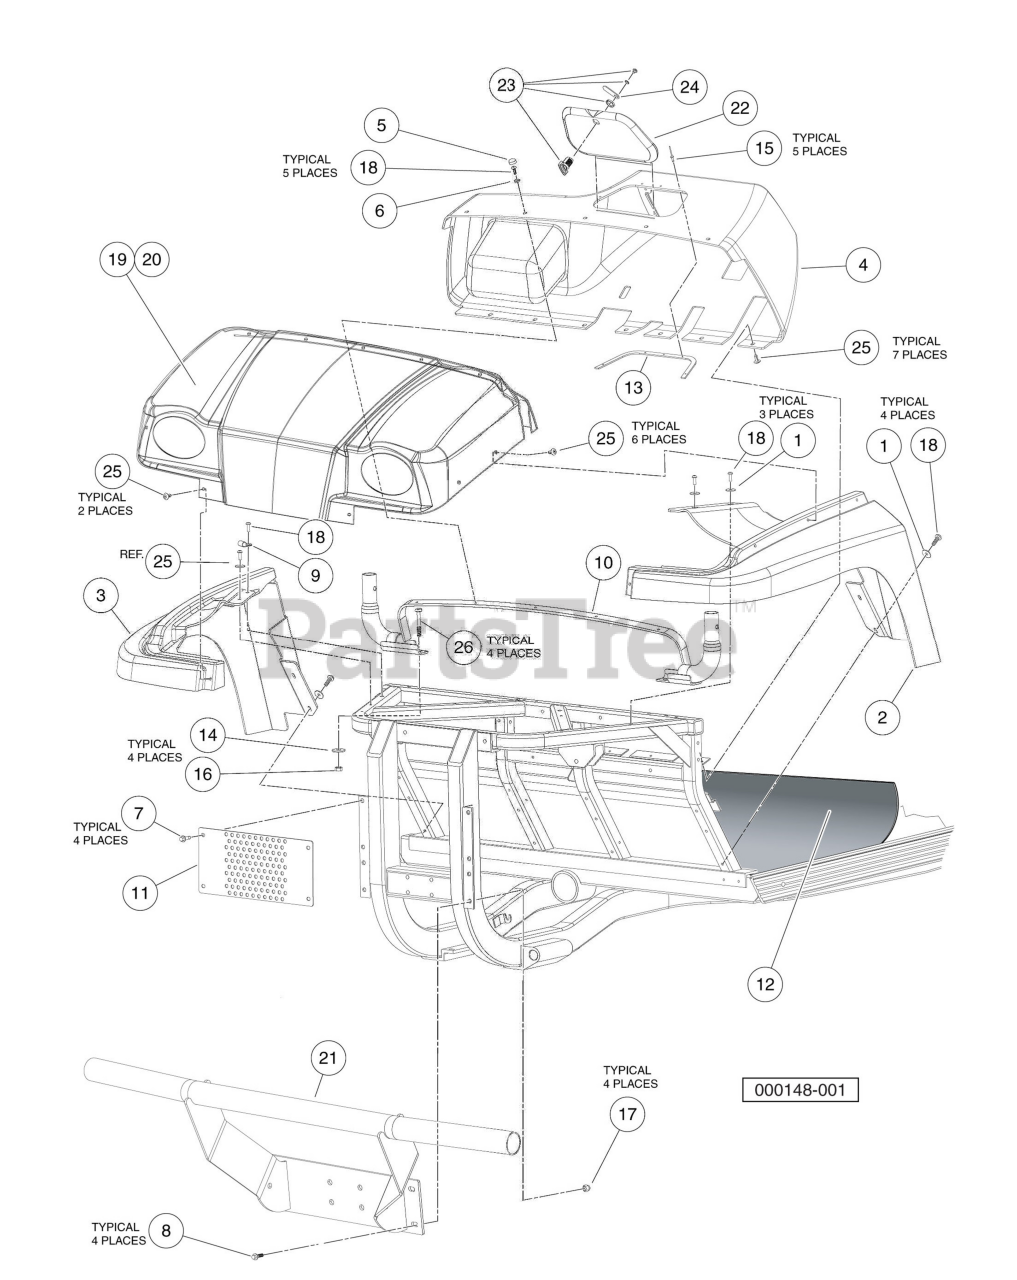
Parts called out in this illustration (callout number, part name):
1	Washer, 1/4" Type B Flat
2	Fender, Left Front
3	Fender, Right Front
4	Dashboard with Access Hole
5	Cap, 1/4" Plastic Screw Head
6	Washer, 1/4 Id Scalloped Plast
7	Screw, M8 X 1.25 X 30 Tri, Blk
8	Bolt, Flange Head, M8 X 30.0
9	P-Clamp, Insulated .312 In
10	Weldment, Support, ROPS
11	Grill, Flat
12	Mat, Floor
13	Support, Access Panel, Dash
14	Washer Hard,m10
15	Rivet, .125" Dia, .311" Panel
16	Nut Flg M10 X 1.5 Mech Def
17	Lock Nut, Flg M8 X 1.25 Nylon
18	Screw, 1/4-20 X 1.0 Pn Hd Torx
19	Cowl, Camo
20	Cowl, Orange
21	Brush Guard
22	Panel, Access, Dash
23	Cam Lock Body
24	Latch, Cam, Access Panel
25	Rivet, Removable, Tuflok 1/4"
26	Bolt, M10 X 1.50 X 65
